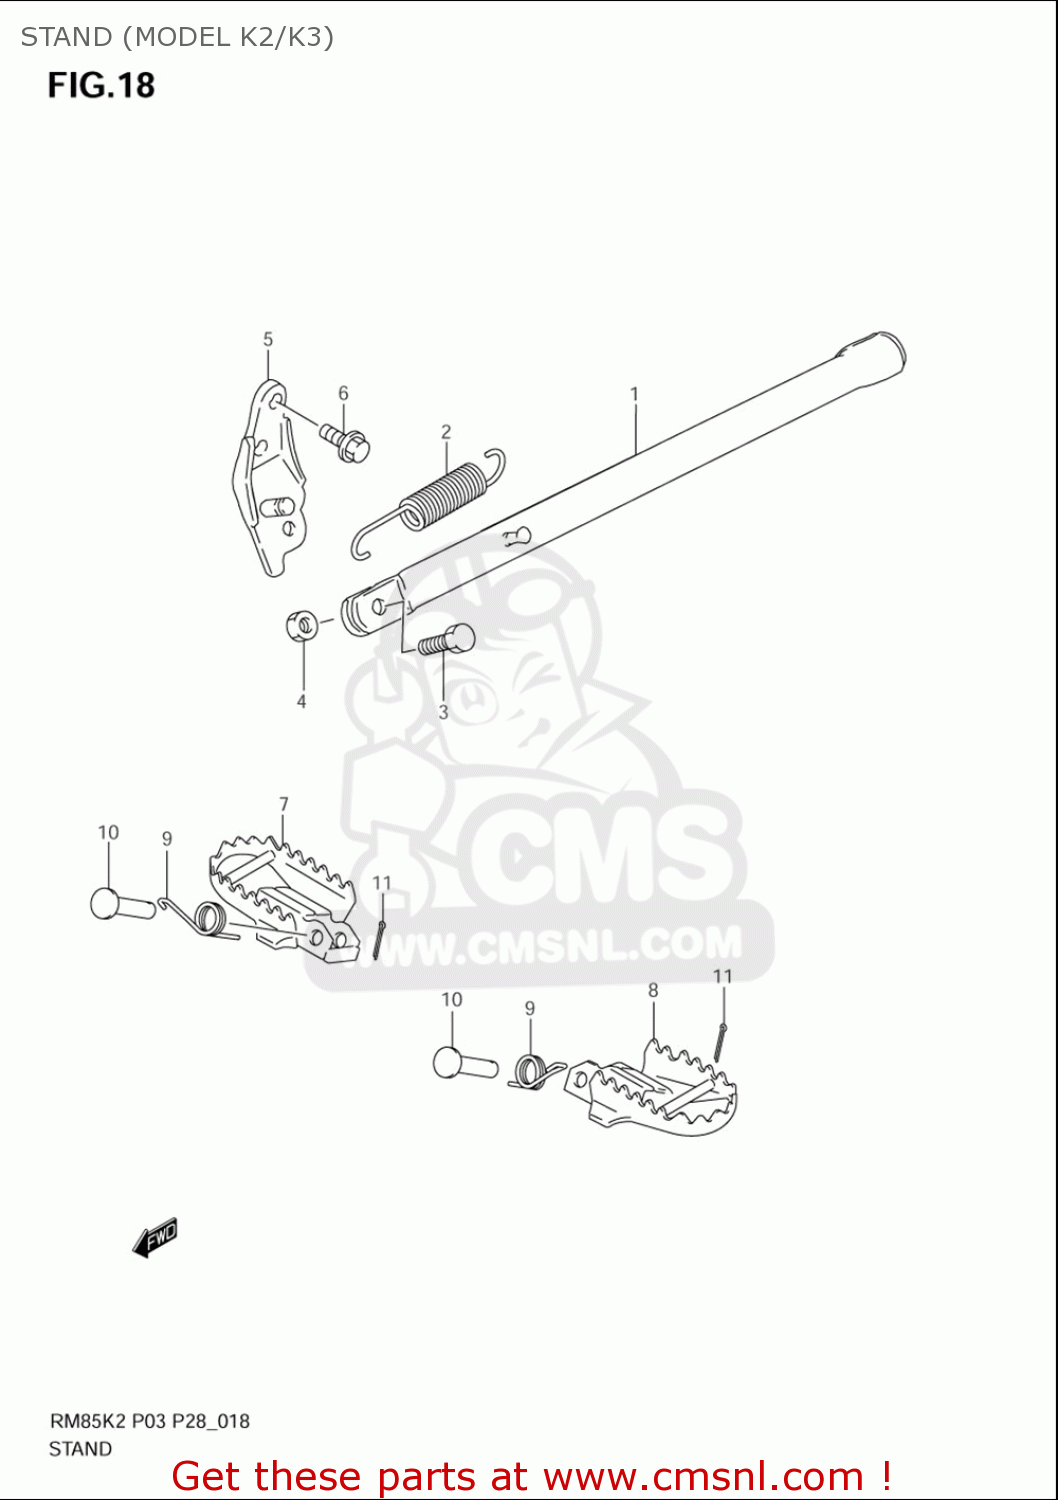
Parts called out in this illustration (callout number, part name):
1	STAND,PROP
2	SPRING
3	BOLT(8X25)
4	NUT
5	BRACKET,PROP STAND
6	BOLT
7	FOOTREST,FR,R
8	FOOTREST,FR,L
9	SPRING
10	PIN
11	PIN
